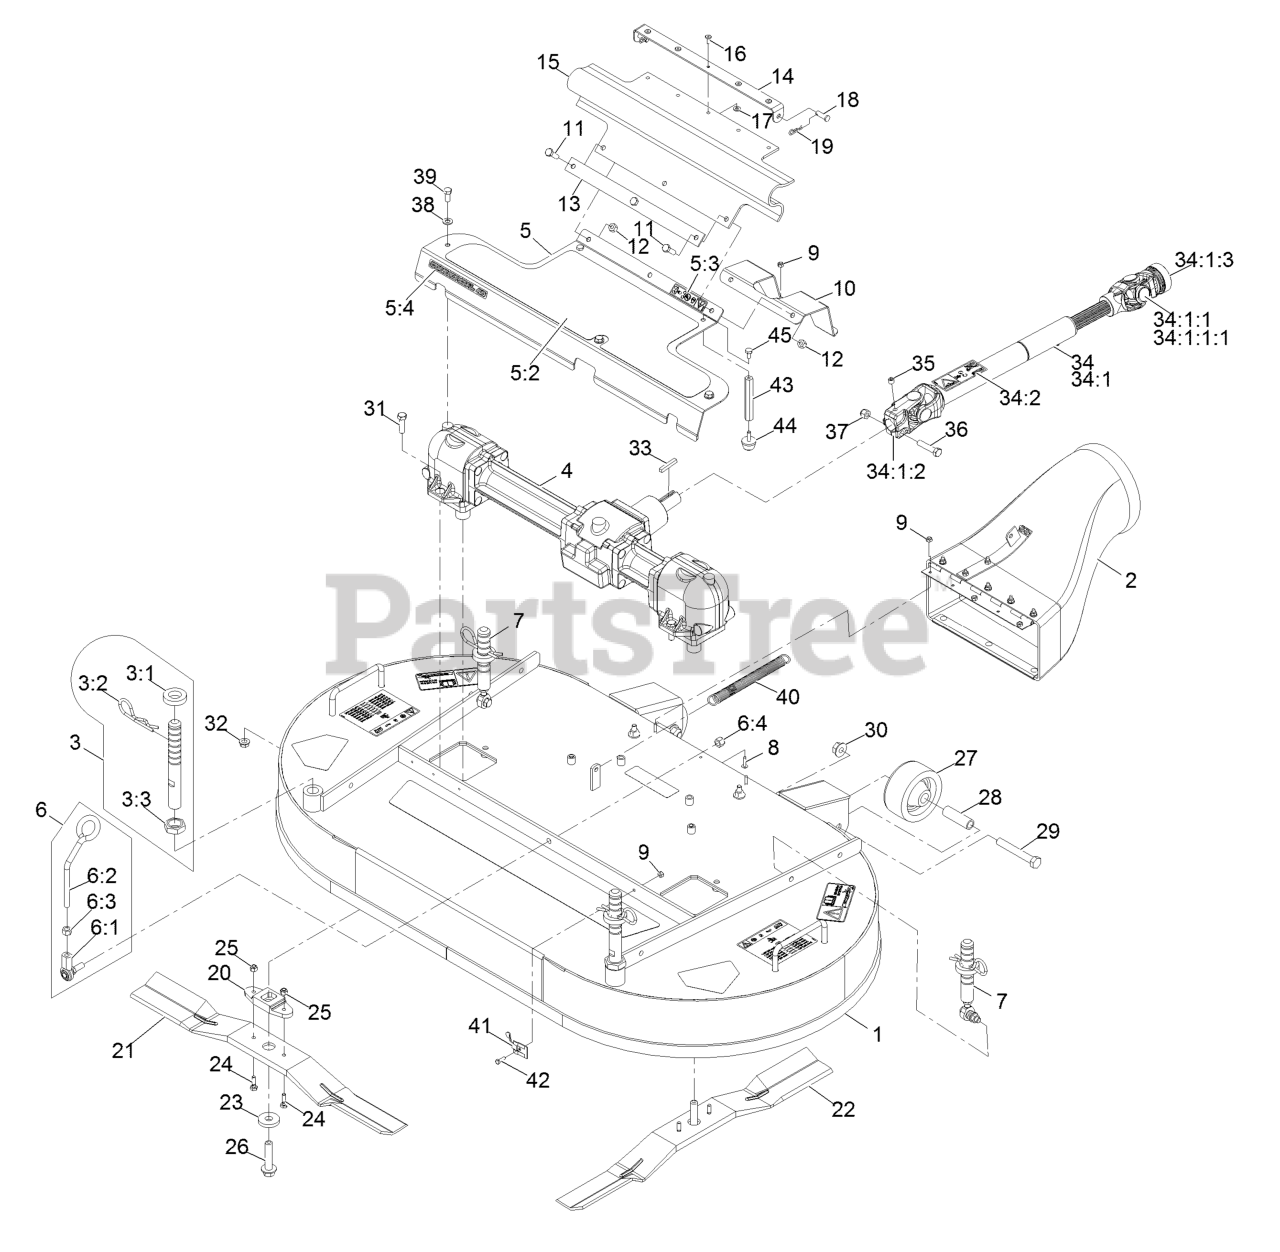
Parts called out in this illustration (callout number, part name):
1	Deck Decal And Baffle ASM
2	Discharge Tube ASM
3	Front Deck Height Adjust ASM
3:1	Spacer-Deck Support
3:2	Pin-Cut Height
3:3	Nut-Jam 7/8-9
4	Gear Box ASM
5	Asm, Gearbox Cover W/Decal (48")
5:2	Pad-Anti Skid
5:3	Decal-Danger
5:4	Decal-Commercial 48
6	Deck Latch ASM
6:1	Balljoint
6:2	Latch-Deck
6:3	Nut-Hex 3/8-24
6:4	Nut-Nyloc 3/8-24
7	Rear Deck Height Adjust ASM
8	Screw-Truss Head #10-24 X 3/4
9	Nut-Nyloc #10-24
10	Guard-Drive Shaft
11	Screw-HH 5/16-18 X 1
12	Nut-Nyloc 5/16-18
13	Strap-Drive, Line Cover
14	Bracket-Guard, PTO
15	Guard-PTO
17	Washer-#10 Std
18	Pin-Clevis 5/16 X 1 49/64
19	Hairpin-Cotter
20	Driver-Blade
21	Blade, RH (48") Red
22	Blade, LH (48") Black
24	Bolt-Shear 1/4-20 X 7/8
25	Nut-Nyloc 1/4-20
26	Bolt-Blade 1/2-20 X 2 1/4
27	Roller-Deck
28	Spacer-Roller
29	Screw-HH 1/2-13 X 3 1/2
30	Nut-Whizlock 1/2-13
31	Screw-HH 3/8-16 X 1 1/4
32	Nut-Whizlock 3/8-16
33	Key-Machine 1/4 X 1/4 X 1 1/2
34	Drive Shaft ASM
34:1	Drive Shaft-Telescoping
34:1:1	U-Joint Kit
34:1:1:1	Fitting-Grease
34:1:2	Yoke-Keyed
34:1:3	Yoke-Quick Disconnect
34:2	Decal-Danger, Driveline
35	Setscrew-3/8-16 X 3/8
36	Screw-HH 3/8-16 X 1 3/4
37	Nut-Nyloc 3/8-16
38	Washer-5/16 SAE
39	Screw-HH 5/16-18 X 3/4
40	Spring-Extension
41	Clip-Deck, Hold Up Rod
42	Screw-HH Machine 10-24 X 5/8
43	Stand-Off
45	Screw-HH 1/4-20 X 1/2
